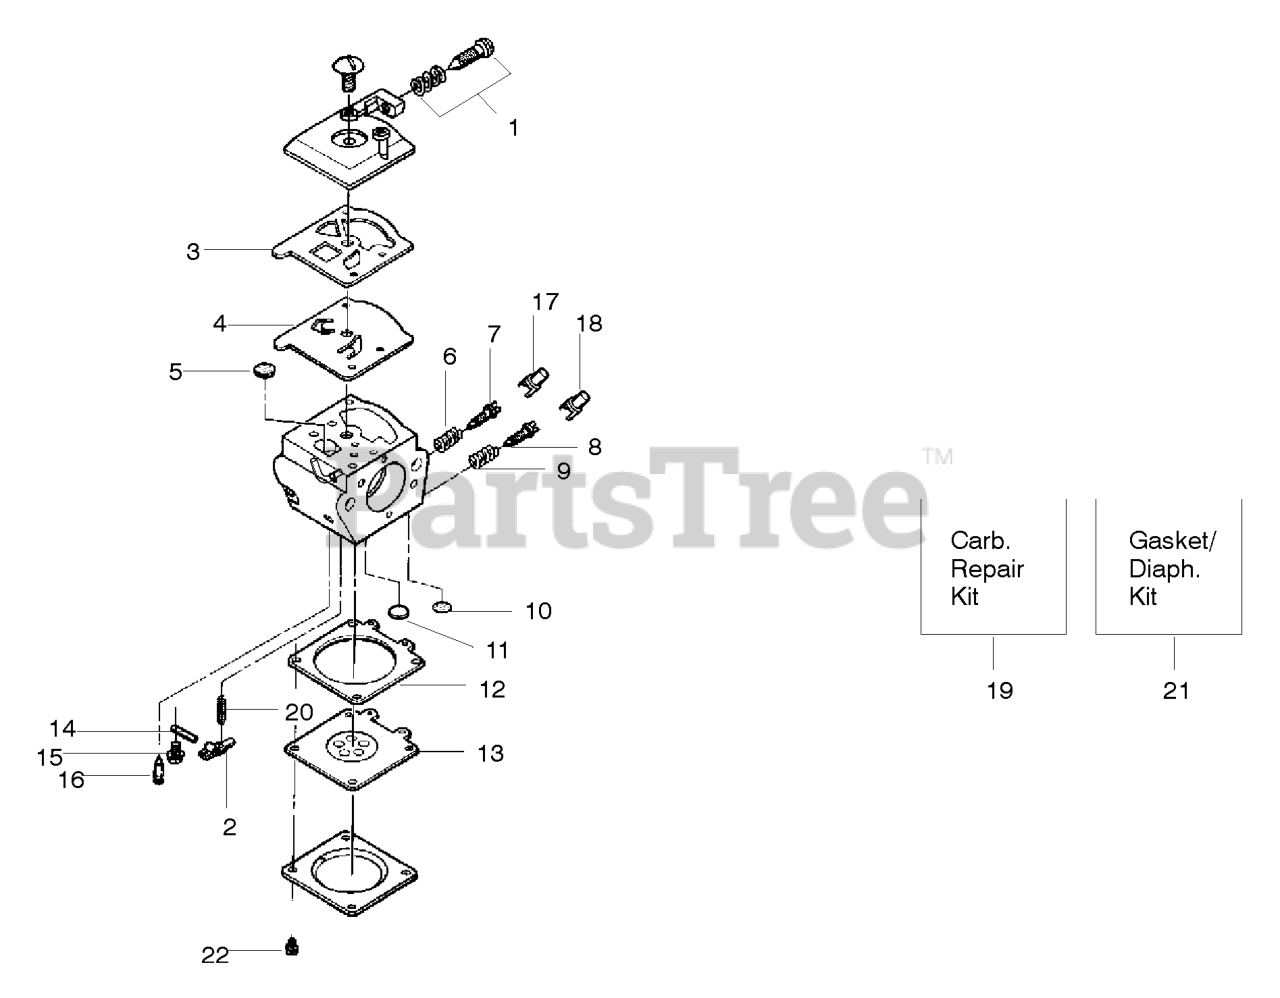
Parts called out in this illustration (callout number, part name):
1	IDLE ADV SCREW KIT
2	LEVER
3	GASKET-FUEL PUMP
4	DIAP FUEL PUMP
5	FILTER SCREEN
6	NEEDLE SPRING
7	LOW SPEED NEEDLE
8	High Speed Needle
9	NEEDLE SPRING
10	Welch Plug (5/16)
12	METERING DIA GASKET
13	DIAPHRAGM
14	PIN
16	INLET NEEDLEVALVE
17	LIMITER CAP-HIGH
18	LIMITER CAP-LOW
19	CARB REPAIR KIT
19	KIT, CARB REPAIR
20	SPRING-METERING LEVER
21	GASKET/DIAPHRAGM KIT
21	GASKET/DIAPHRAGM KIT ZAMA
22	SCREW, MOTOR COVER
